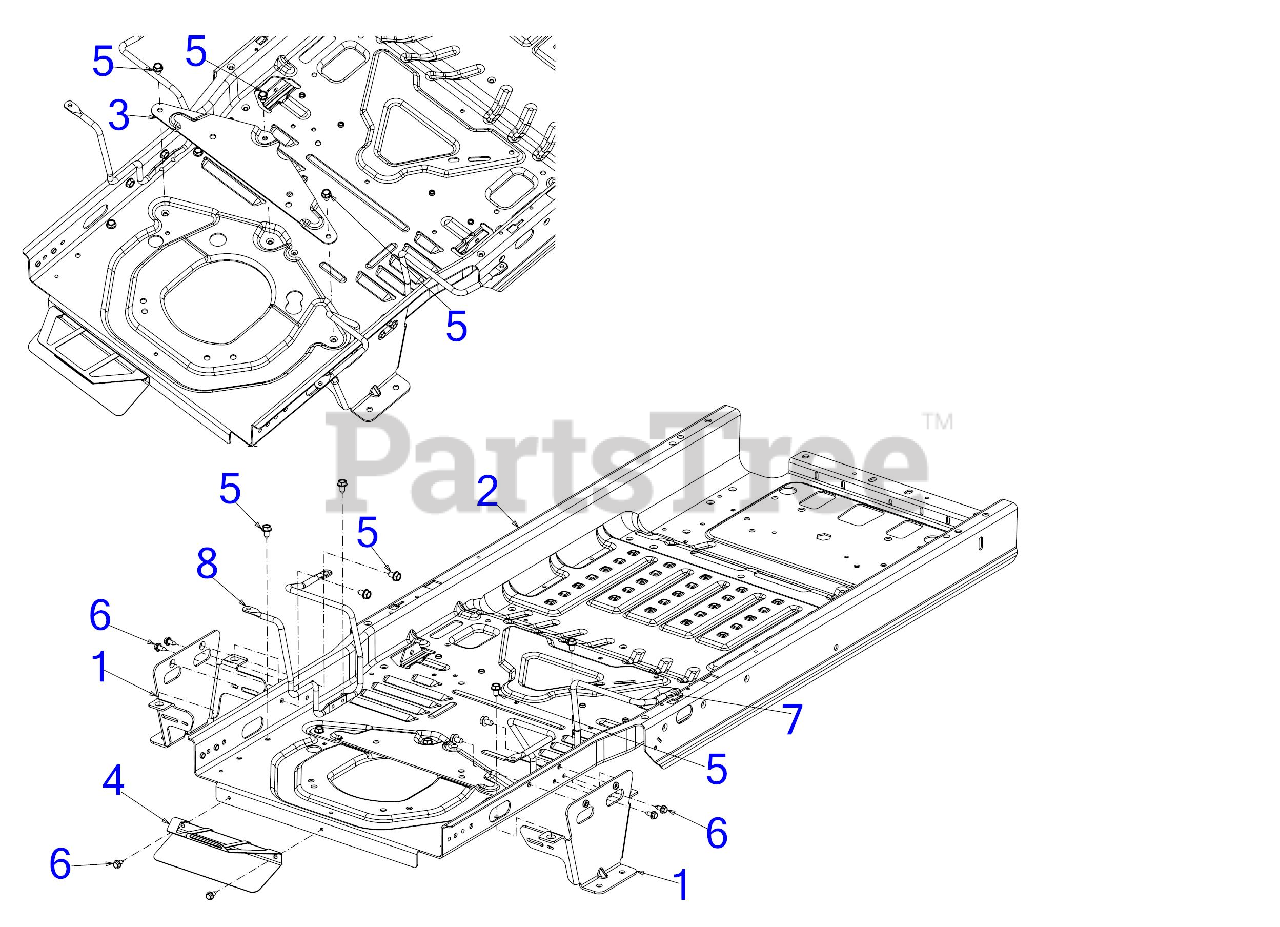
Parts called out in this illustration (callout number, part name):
5	SCREW 5/16-18 x .625
6	SCREW 1/4-20X.625
7	POD SUPPORT ROD (RH)
8	POD SUPPORT ROD (LH)
